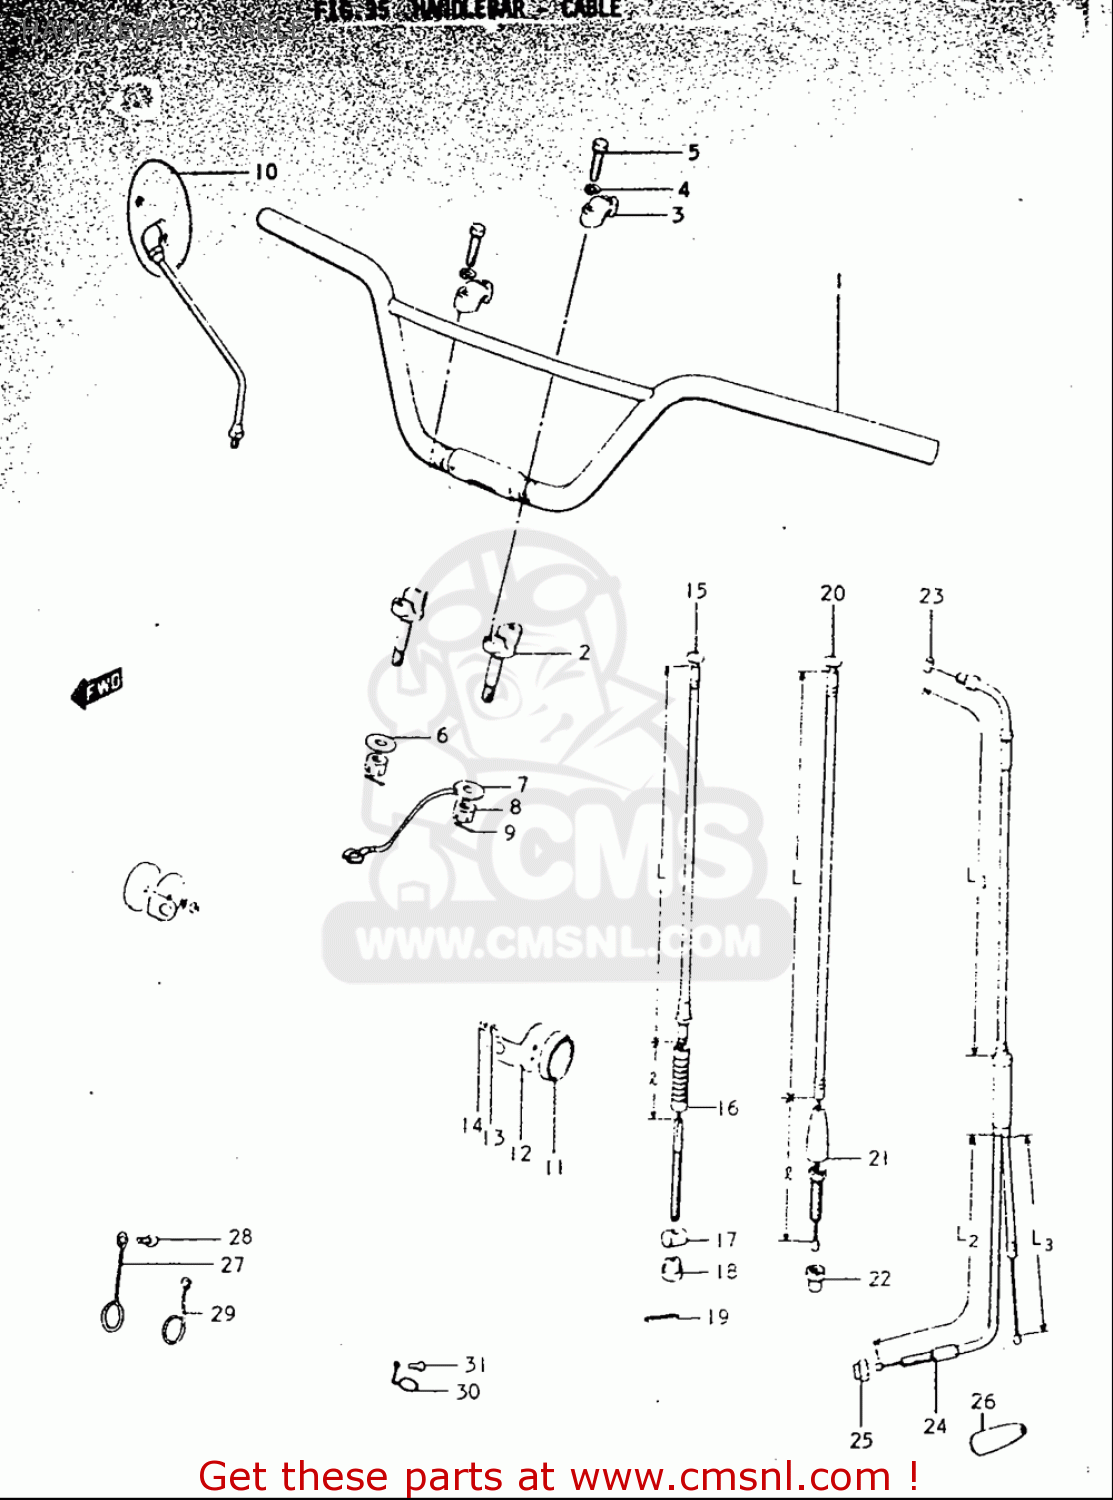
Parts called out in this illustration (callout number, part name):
1	HANDLEBAR
3	HOLDER,HANDLEBAR
4	WASHER,LOCK
5	BOLT
6	WASHER(10.5X28X2.3)
8	NUT
13	WASHER,LOCK
14	NUT
16	SEAL,DUST
17	PIN(13X18)
18	NUT
20	CABLE,CLUTCH
22	NUT
24	BOLT
25	NUT
